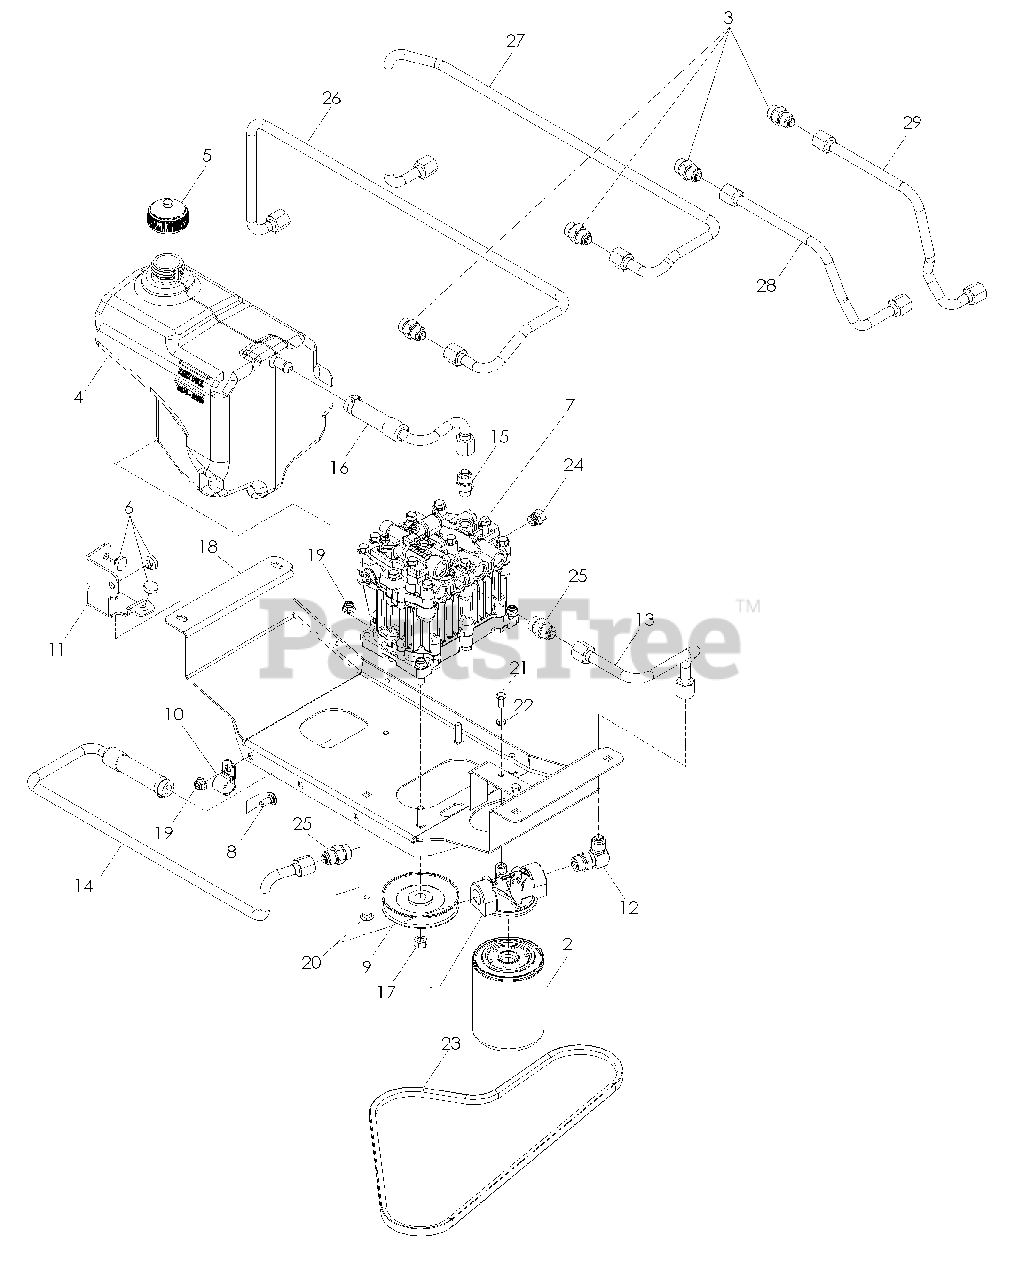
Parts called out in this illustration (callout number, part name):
1	FILTER HEAD
2	HYDRAULIC OIL FILTER
3	FITTING, STRAIGHT F6400-8-8-0
4	RESERVOIR HYDRO
5	HYDRAULIC CAP
6	GROMMET, BUMPER
7	PUMP, DUP10S (77808041201)
8	BOLT 5/16C X 3/4" CARRIAGE
9	PULLEY, PUMP
10	LOOM CLIP
11	SUPPORT, RESERVOIR
12	FITTING, 10-8 90 DEG
13	HYD LINE, CHARGE
14	HYD LINE, INLET
15	FITTING, HYDRO
16	HYDRO LINE, CASE
17	NUT M10-1.5 L/H HEX
18	PLATE, PUMP
19	5/16-18 NYLOC FLANGE NUT
20	BOLT, CARRIAGE 5/16X1-1/4
21	HCS 1/4C X 5/8
22	LOCKWASHER 1/4"
23	IZT BELT
24	PLUG, 6408-6
25	FITTING, 10-8 STRAIGHT
26	HYDRO LINE, A
26	HYDRO LINE, 72A
27	HYDRO LINE, B
27	HYRO LINE, 72B
28	HYDRO LINE, C
28	HYDRO LINE, 72C
29	HYDRO LINE, D
29	HYDRO LINE, 72D
